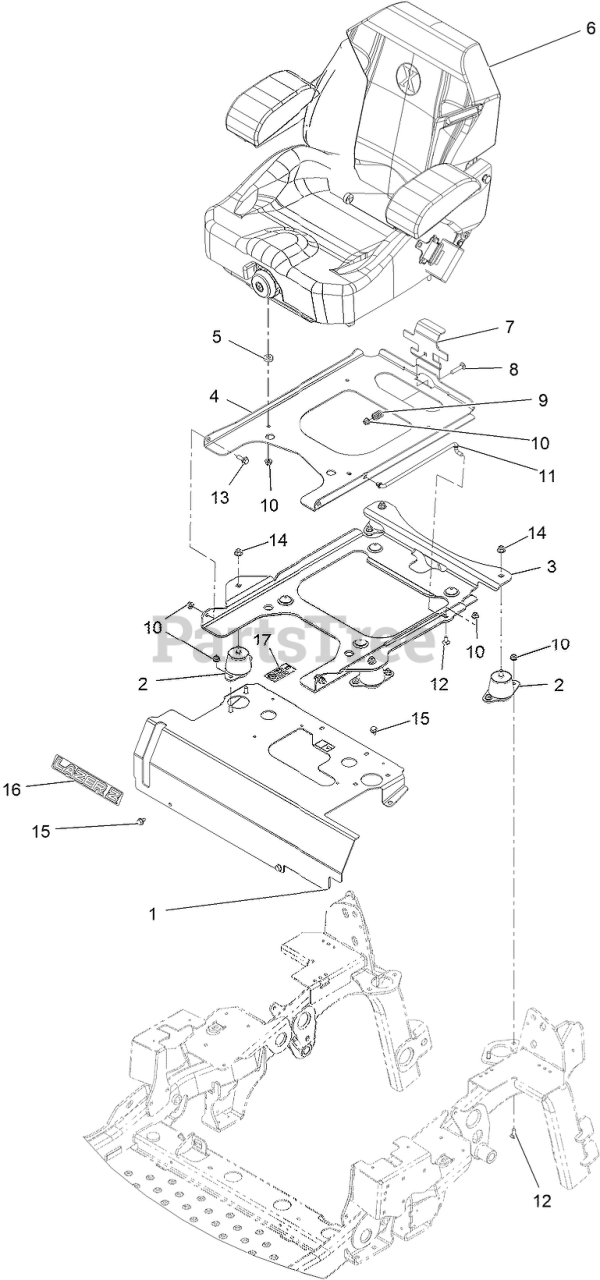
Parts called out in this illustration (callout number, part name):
1	MOUNT-SEAT W/DECALS
2	ISOLATOR-SEAT
3	PLATE-SUPPORT, TILT SEAT
4	PLATE-FRAME, SEAT
6	KIT-SUSPENSION SEAT
7	PLATE, SEAT LATCH
8	BOLT-CARR
9	SPRING-COMPRESSION
10	NUT-HF, NI
11	ROD-PROP
12	SCREW-CARR
13	SCREW-SHOULDER
14	NUT-HF, NI
16	DECAL, LAZER MODEL
17	DECAL-TRANS FLUID
